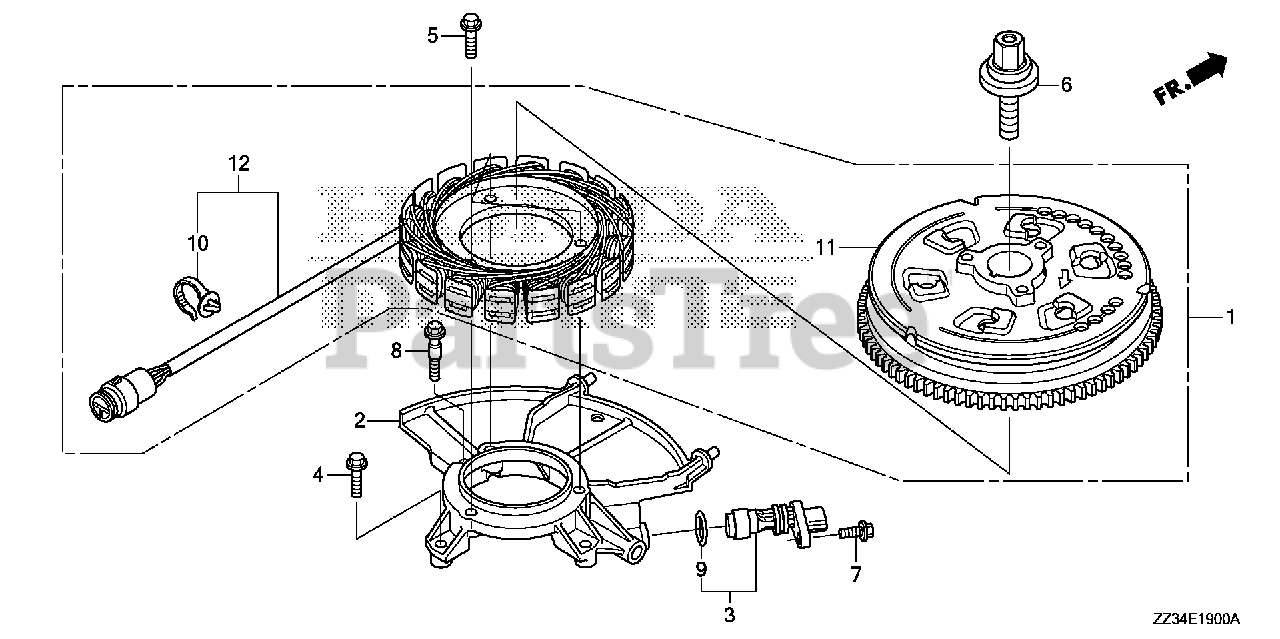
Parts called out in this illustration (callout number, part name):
1	ALTERNATOR ASSY.
2	BRACKET, ALTERNATOR
3	SENSOR ASSY., CRANK
4	BOLT, FLANGE (6X25)
5	BOLT, FLANGE (6X28)
6	BOLT-WASHER (16X49)
7	BOLT, FLANGE (6X16)
8	BOLT, SPECIAL (6X31)
9	O-RING (15X1.9)
10	CLIP, HARNESS BAND (96.9MM) (NATURAL)
